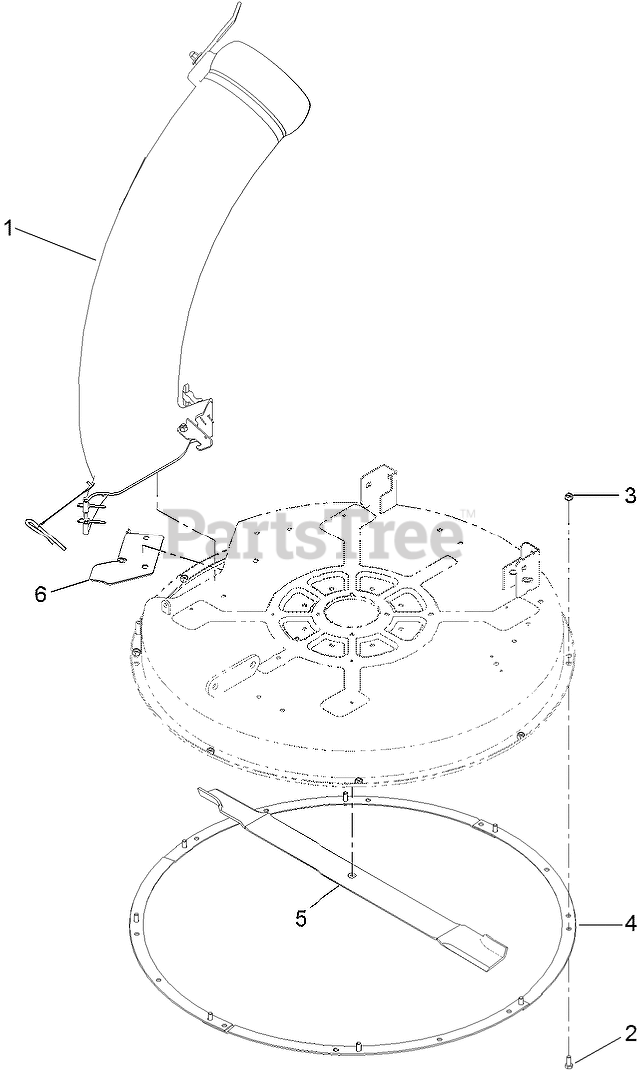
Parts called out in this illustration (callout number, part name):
1	32 INCH CHUTE ASM
2	SCREW-HH
3	NUT-LOCK, NI
4	RING-DECK
6	BRACKET-CUTOFF
